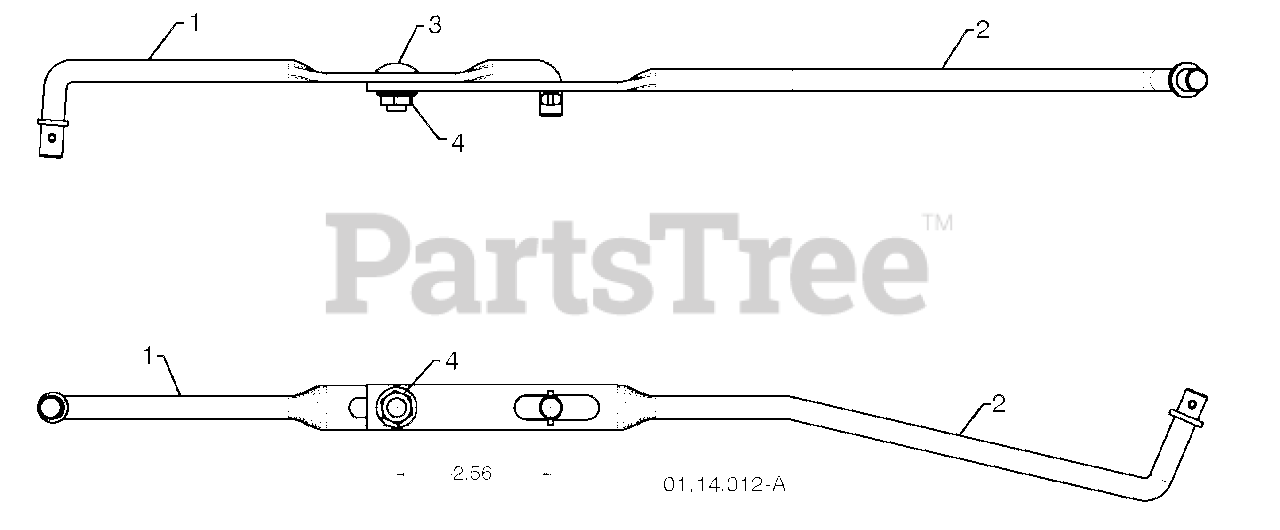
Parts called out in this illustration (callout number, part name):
1	SHIFTER ROD TOP
2	SHIFTER ROD BOTTOM
3	CARRIAGE BOLT 5/16-18 X .75
4	NUT 5/16-18
